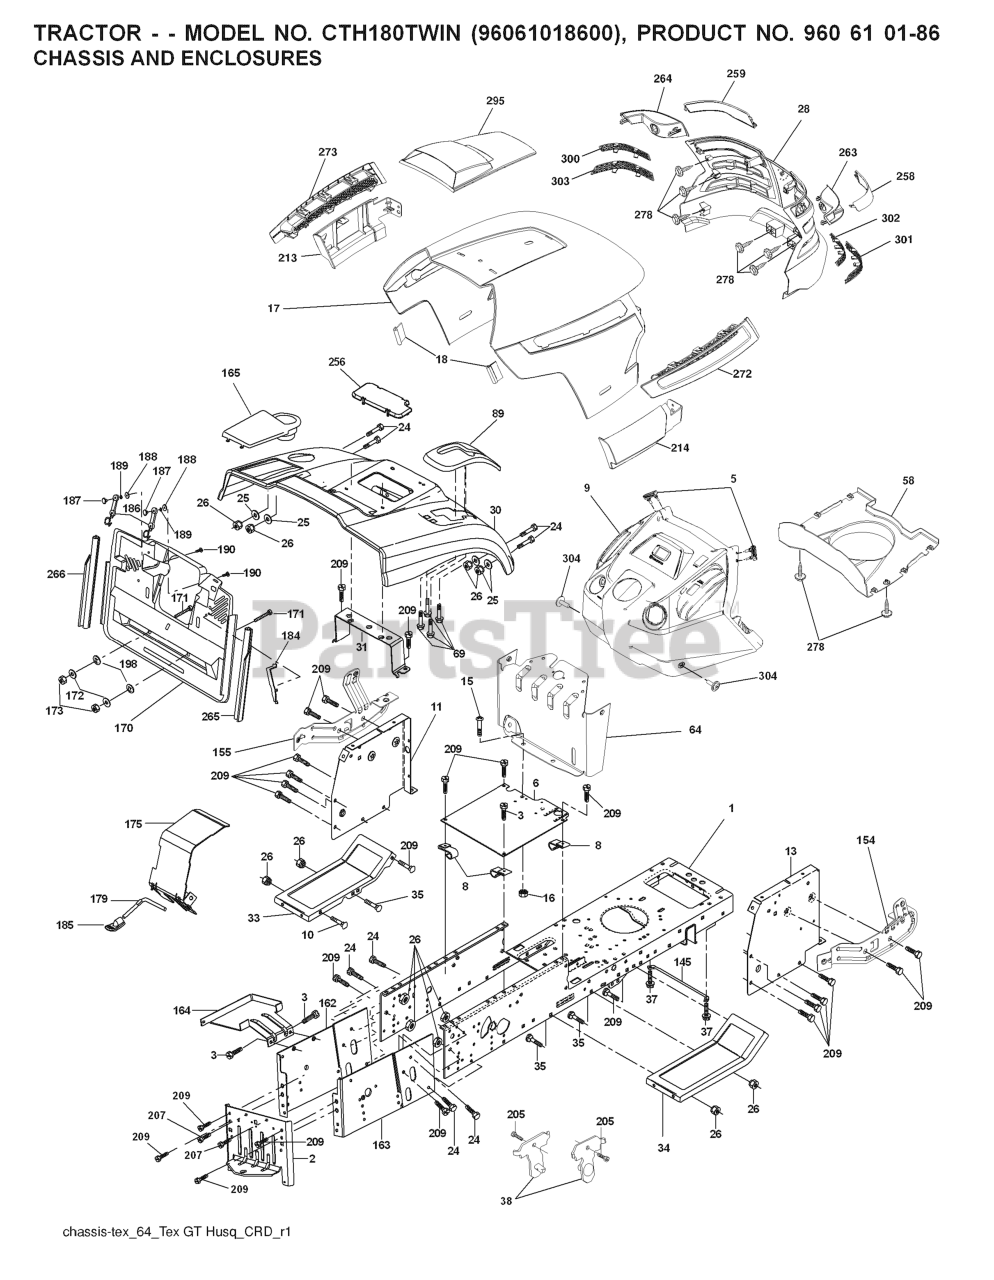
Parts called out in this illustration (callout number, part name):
2	DRAWBAR
3	SCREW 3/8-16X3/4
5	BUMPER DASH
6	PLATE
8	CLIP,INSULATOR
10	BOLT D
11	PANEL DASH LH
13	PANEL DASH RH
15	Screw, Machine, Truss Head 5/16-18 UNC x 3/4
16	NUT
17	HOOD
18	BUMPER.HOOD.TEX.HUSQVARNA
25	WASHER
26	NUT
28	GRILL.ASM.HUSQ.TG/CRD.W/TRIM
30	CONSOLE.CRD.AUTO.GRY
31	BRACKET SUPPORT FENDER
33	FOOTREST PNT LH
34	FOOTREST PNT RH
37	Screw 5/16-18 x 1/2 Hex, Self Tapping 5/16-18 x 1/2
38	BRACKET ASM PIVOT MOWER REAR
58	AIR.DUCT.TEXGT.HUSQ.SV
69	SCREW.HI-LO.CONSOLE
89	CONSOLE.CRD.AUTO.GREY.2005
145	ROD PIVOT CHASSIS/HOOD
162	BRACKET
163	BRACKET EXTEN CHASSIS RH CRD
165	RP.COVER.BATTERY.CRD.GREY
172	WASHER
175	DOOR TRAP
179	ROD PIVOT FBI
184	BRACKET.ACTUATOR.BAGGER.SRD
186	LATCH ASSY
187	WELDNUT
189	LOCKWASHER #10
190	SCREW
207	SCREW, 5/16-18 X 1/2
209	SCREW, 3/8-16X3/4
213	SKIRT.HOOD.SIDE.HUSQ.LH.GREY
214	SKIRT.HOOD.SIDE.HUSQ.RH.GREY
256	COVER FENDER CRD
258	LENS.RH.TEX.GT.HUSQ.CL
259	LENS.LH.TEX.GT.HUSQ.CL
263	BEZEL.RH.TEX.GT.HUSQ
264	BEZEL.LH.TEX.GT.HUSQ
265	SEALING
266	SEALING
272	VENT.SIDE.HOOD.HUSQ.RH.GREY
273	VENT.SIDE.HOOD.HUSQ.LH.GRAY
278	SCREW
295	VENT.ASM.HOOD.TOP.TEX.
300	INSERT.HEX.GRILL.HUSQ.
301	INSERT.HEX.GRILL.HUSQ.GREY
302	INSERT.HEX.GRILL.HUSQ.
303	INSERT.HEX.GRILL.HUSQ.
304	SCREW 14-20 X 5/8
